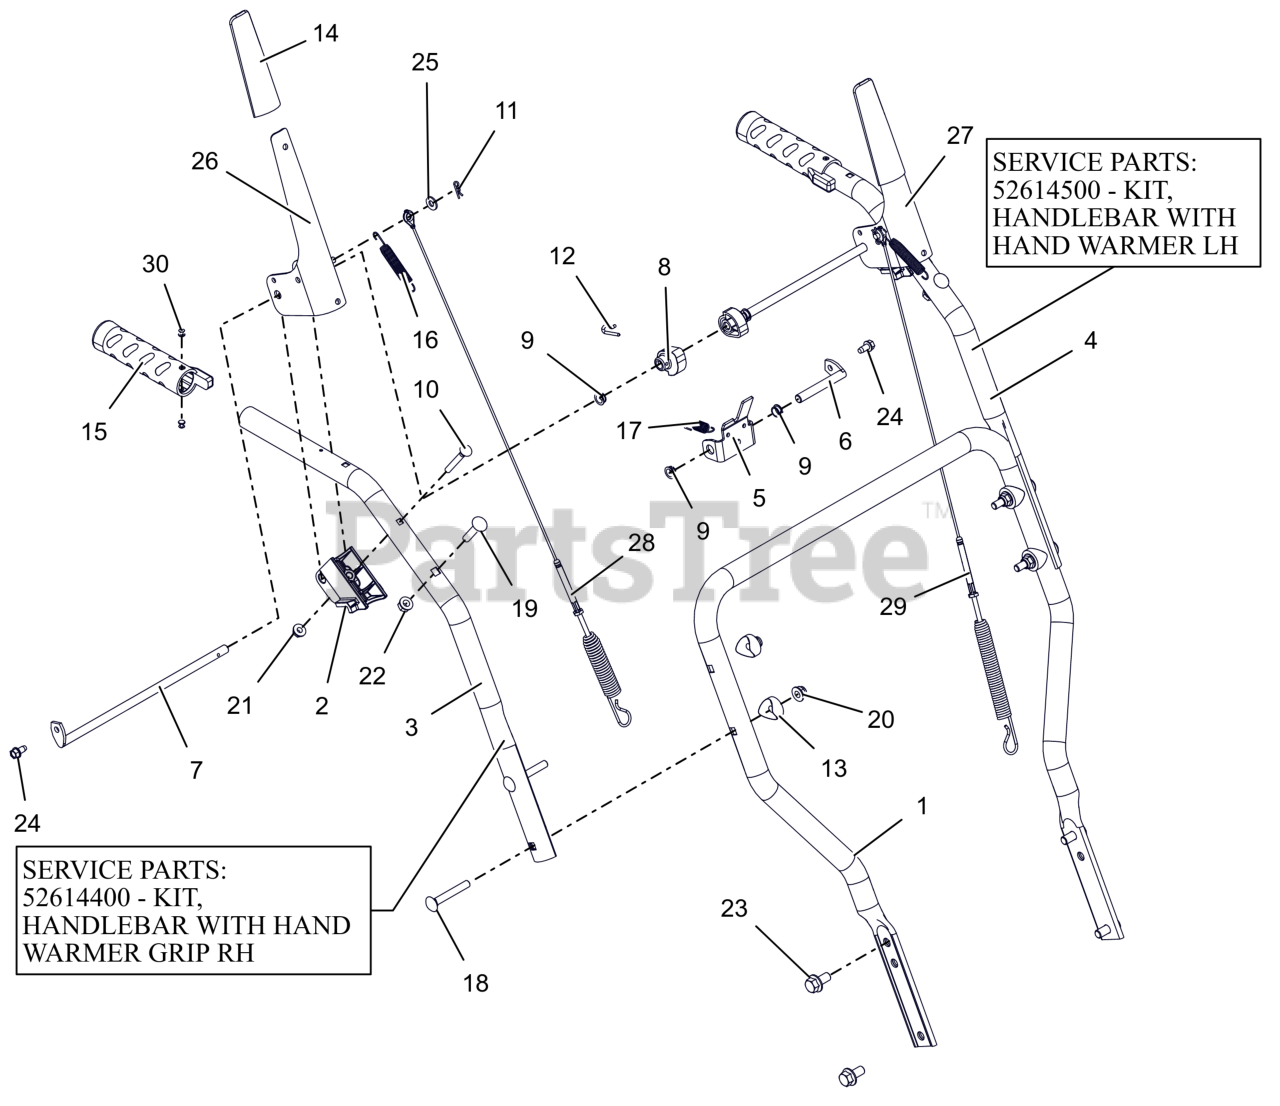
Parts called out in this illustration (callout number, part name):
1	HANDLEBAR, LOWER
2	BLOCK, CLUTCH PADDLE
3	HANDLEBAR, UPPER - RH
3	KIT, HANDLEBAR HW RH
4	HANDLEBAR, UPPER - LH
4	KIT, HANDLEBAR HW LH
5	BRACKET, INTERLOCK ARM
6	ROD, PIVOT - INTERLOCK
7	ROD, PADDLE MOUNT - PRO
8	CAM, INTERLOCK
9	BUSHING, POLYLINER-.38 SNAPIN
10	BLT-RDHDXLSQNK .25-20X2.0 G5YZ
11	PIN, HAIR #178 .06X.77 ZCC
12	PIN, SPRING CLIP
13	SPACER, HANDLEBAR
14	SLEEVE, CLUTCH PADDLE-GRAY
15	GRIP,HEATED HANDLE-GRAY
16	SPRING, EXTENSION
17	SPRING-EXT .047X.438X1.45
18	BLT, RHSN .31-18X2.25 G5 ZCC
19	BLT,RHSN .31-18X1.50 G5 ZCC
20	NUT,LK-NYL-FLG .31-18 G5ZC120
21	NUT-LK-CTR-FLG .25-20 ZC120
22	NUT-LK-TOP-FLG .312-18 GF ZCC
24	SCR-TAP .25-20X.50 HWH ZCC
25	WSHR,FLT .281X.625X.065 ZCC
26	LEVER, CLUTCH-RH
27	LEVER, CLUTCH-LH
28	CABLE, AUGER (DELUXE & PRO)
29	CABLE, UPPER TRACTION
30	RVT-POP #43 .125X.313 STL ZINC
